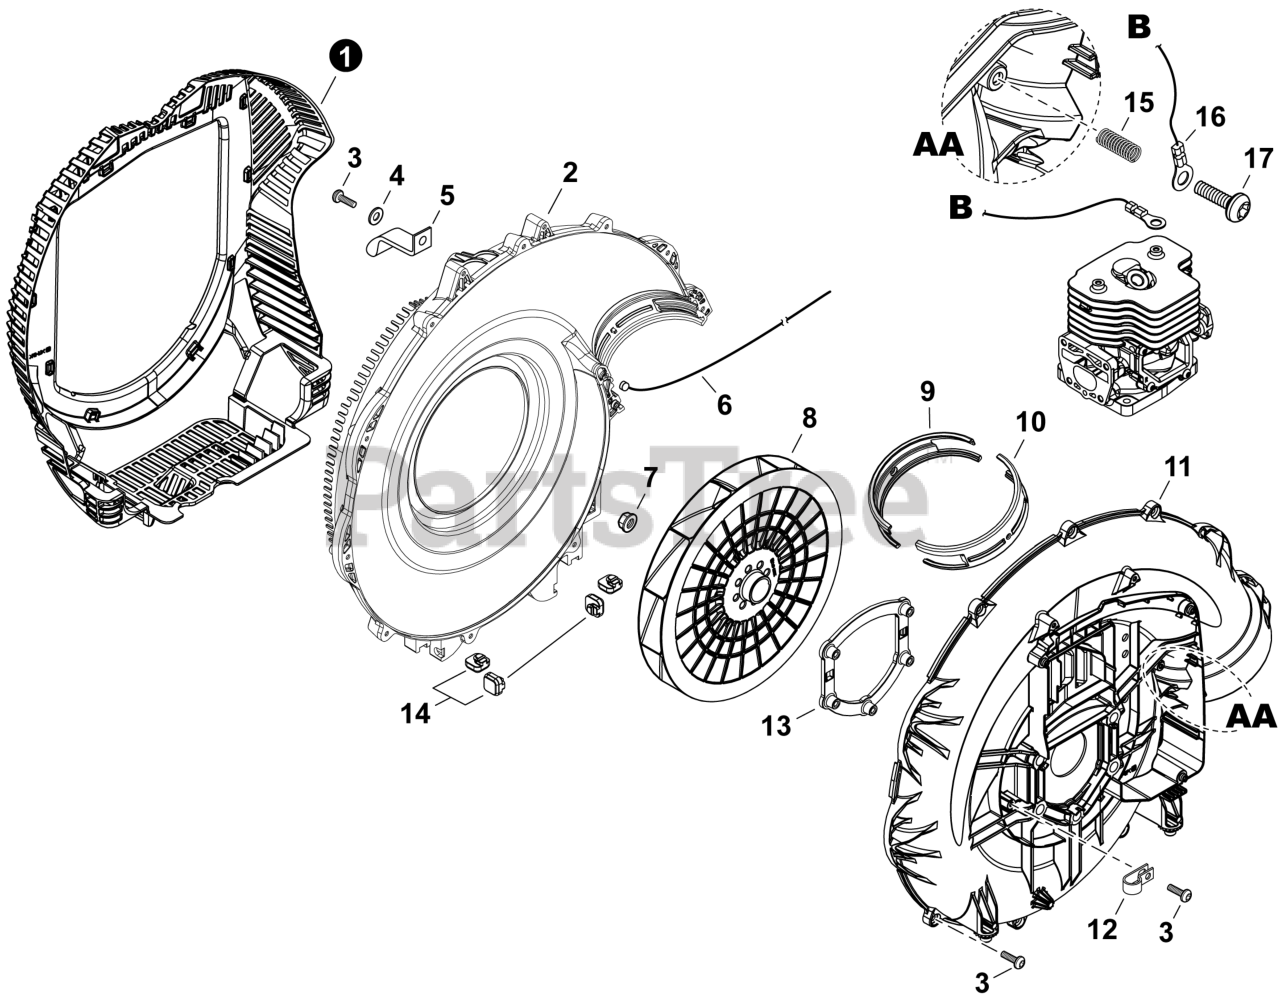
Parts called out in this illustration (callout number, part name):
1	GUARD, DEBRIS
2	COVER, FAN
3	BOLT, TORX 5x20
4	WASHER 5.5x16x0.8
5	STRAP, SAFETY
6	WIRE, ANTI-STATIC
7	NUT, FLANGE 10x1.25
8	FAN, BLOWER
11	CASE, FAN
12	CLIP
13	PLATE, ENGINE
14	CUSHION
15	SPRING, COMPRESSION
17	BOLT, TORX 5x12
